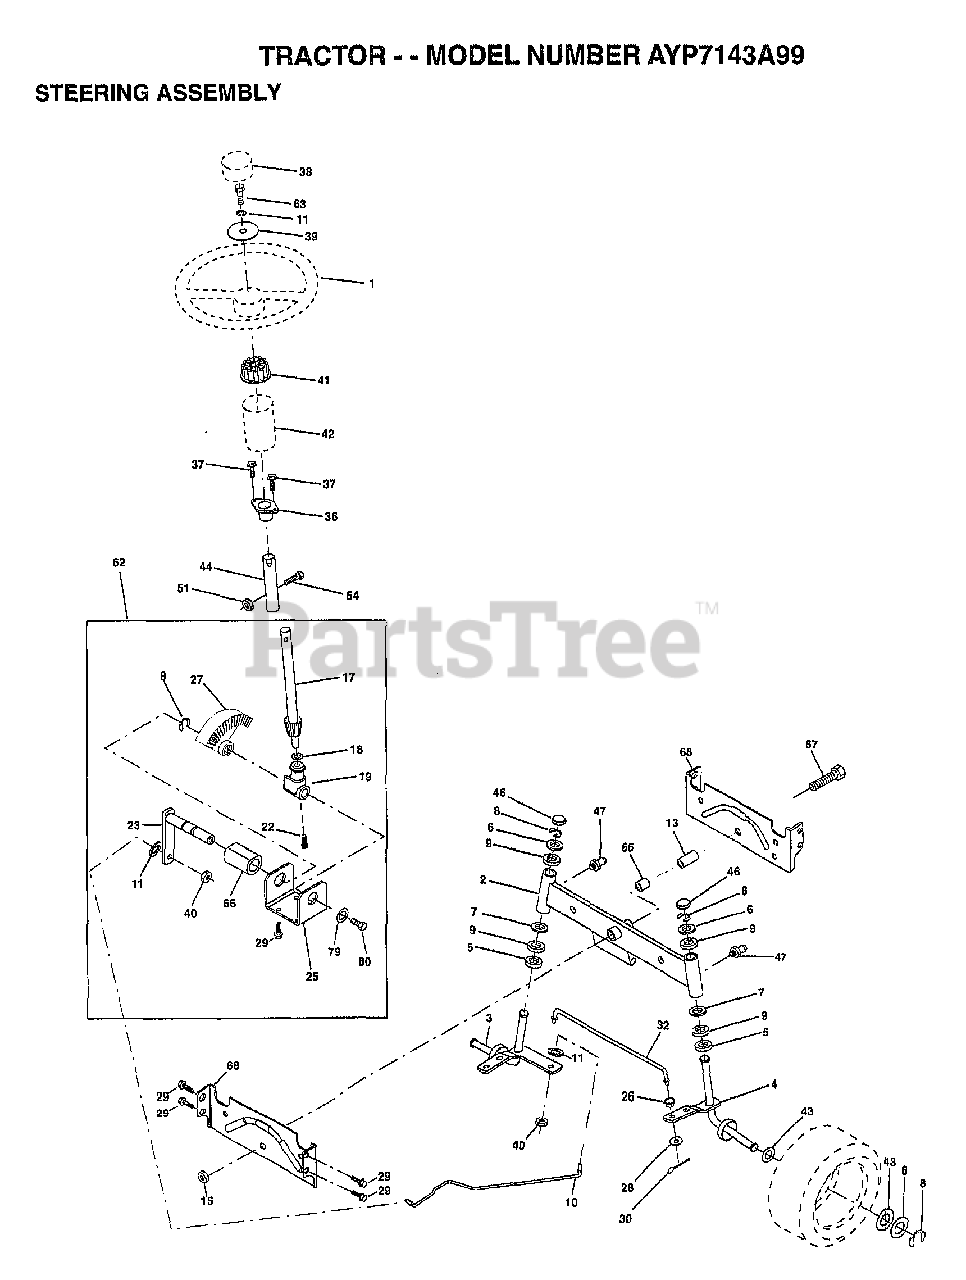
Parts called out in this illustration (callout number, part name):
1	WHEEL STR AYP BLK
2	AXLE ASM
3	SPINDLE.ASM.LH
4	"SPINDLE ASM,RH"
5	WASHER .T
6	WASHER
7	WASHER
8	RING
9	COL. SRTG. BEAR.
10	DRAGLINK-STAMPED
11	LOCKWASHER
13	BEARING AXLE
15	"NUT-LOC,FLANGE LT"
17	SHAFT ASM STEERIN
18	THRUST WASHER
19	SUPPORT.SHAFT.STEER
22	SCREW.HX.WSH.HD
23	SHAFT ASM PITTMAN
25	BRKT-STEERING
26	BUSHING.DRAGLINK
27	GEAR SECTOR
28	WASHER
29	SCREW
30	COTTER PIN
32	TIE ROD
36	BUSHING.STEERING
37	"SCREW-TT,10-32 FL"
38	CAP STEER AYP
39	WASHER T
40	GRIPCO NUT
41	ADAPTER LT
42	BOOT.STEER.PL
43	WASHER
44	EXT SHAFT STEERIN
46	CAP
47	ZERK M
51	NUT
54	BOLT
62	KIT.STEER.ASM
63	BOLT
65	SPACER AXLE
66	"BEARING-ARM,PITMA"
67	BOLT
68	BRACE AXLE
79	WASHER
80	BOLT.HX.NYLON3/8-16X3/
